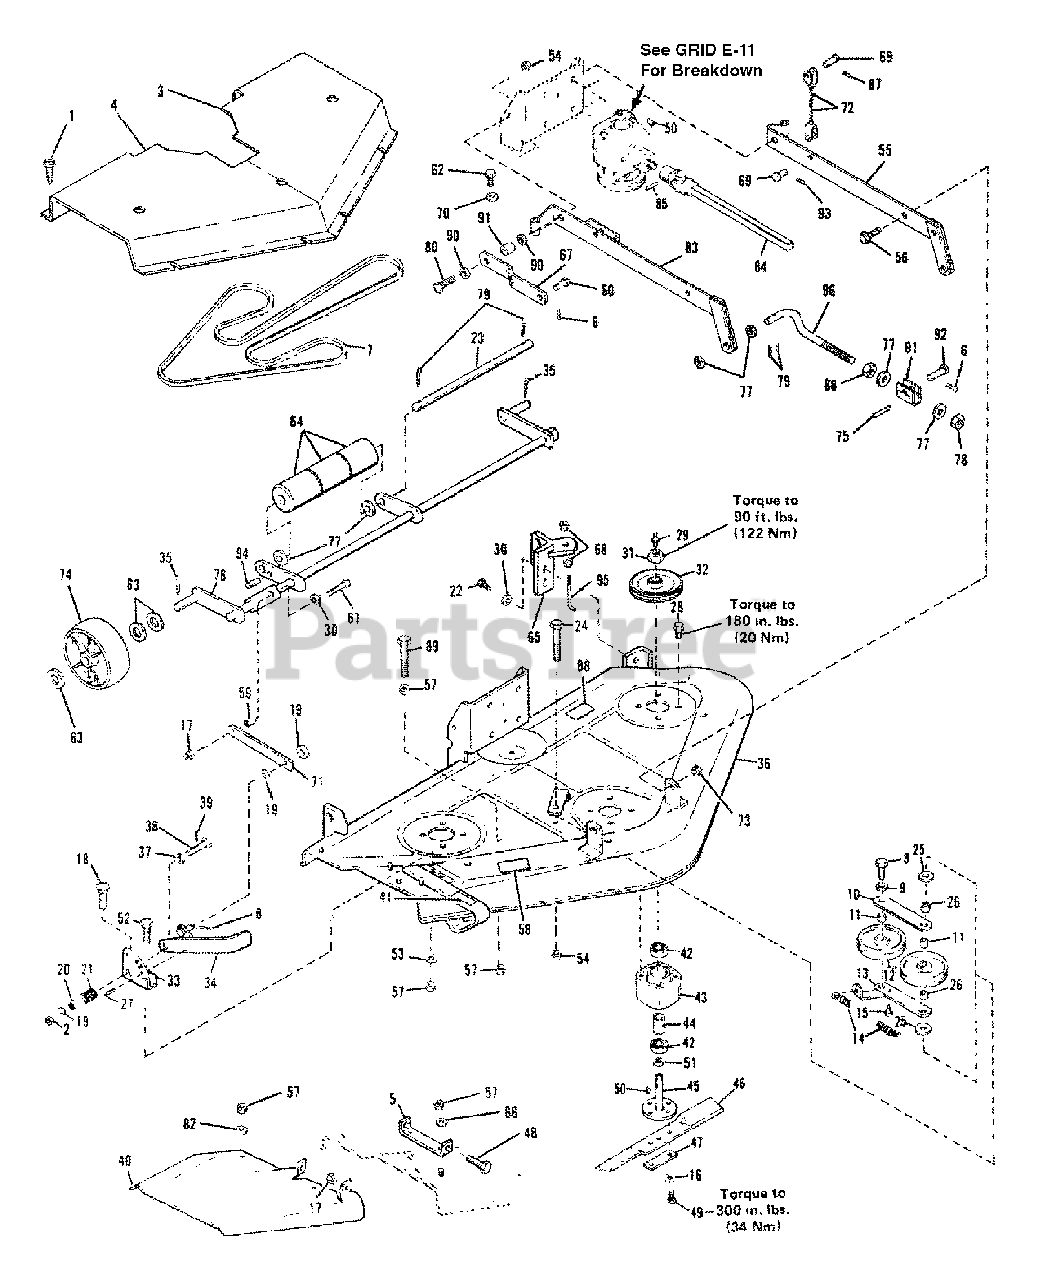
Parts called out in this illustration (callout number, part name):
1	Self Driving Screw, 10,24 x 5/8
2	Lock Nut, 1/2-13
3	Belt Cover, LH
4	Belt Cover, PH
5	Hinge Bracket
6	Spring Clip
7	V-Belt (137")
8	Capscrew, Hex Hill
9	Lockwasher, 1/2
10	Idler Arm
12	Idler Pulley
13	Idler Arm
14	Extension Spring
15	Wear Button
16	Lockwasher, 3/8
17	Lock Nut, 3/8-16
18	Carriage Bolt, 5/16-18 x 3/4
19	Flat Washer, 1/2
20	Spacer
21	Spring
22	Hex Screw 3/8-16 x 1
23	Axle Roller
24	Capscrew, 1/2-13 x 2-34
25	Thrust Washer
26	Bearing Sleeve
27	Drive Pin, 5/16-18 x 3/4
28	Flange Screw, 5/16-18 x 3/4
29	Grease Fitting
30	Flat Washer 3/8
31	Locknut, 3/4-16
32	Blade Sheave
34	Handle Assembly
35	Cotter Pin. 1/8 x 1
36	Mower Base Assembly
37	Flat Washer, 1/2
38	Special Screw
39	Roll Pin, 3/16 x 7/8
40	Discharge Chute
41	Decal, Cutting Line
42	Bell Bearing
43	Spindle Housing
44	Spacer
45	Shaft Assembly
46	Blade
47	Plate
48	Hex Screw, 5/8-16 x 7/8
49	Capscrew 3/8-24 x 1
50	Woodruff Key 3/16 x 3/4
51	Flat Washer. Special
52	Hex Capscrew, 5/16-18 x 3/4
53	Flat Washer, 5/16
54	Lock Nut. 1/2-13
55	Support Assembly LH
56	Flange Screw 3/8-16 x 1
57	Top Locknut, 5/16-16
58	Caution Decal
59	Spacer
60	Clevis Pin
61	Capscrew, W8-16 x 1-1/2
62	Flange Screw 3/8-16 x 2
63	Flat Washer, 5/8
64	Roller
65	Shaft Support Assembly
66	Flat Washer 5/16
67	Drag Link
68	Jam Nut 3/8-16
69	Clevis Pin
70	Hex Nut. 3/8-16
71	Link, Connecting
72	Lift Cable
73	Flange Nut 3/8-16
74	Gage Wheel
75	Roll Pin
76	Pivot Shaft Assembly
77	Flat Washer
78	Hex Nut 3/4-10
79	Cotter Pin, 1/6 x 1-1/4
80	Hex Screw 1/2-13 x 1-3/4
81	Hitch Bracket
82	Flat Washer
83	Support Assembly RH
84	Drive Assembly
85	Roll Pin. 3/16 x 1-1/2
86	Hex Nut 3/4-10
87	Cotter Spring
88	Set Drive Decal
89	Hex Screw 5/16-18 x 1-1/4
90	Flat Washer, 1/2
91	Spacer
92	Clovis Pin
93	Cotter Pin, 3/32 x 3/4
94	Drive Pin. 1/8 x 3/4
96	Hitch Link
NI	Dark Green Spray Paint 13 oz.
